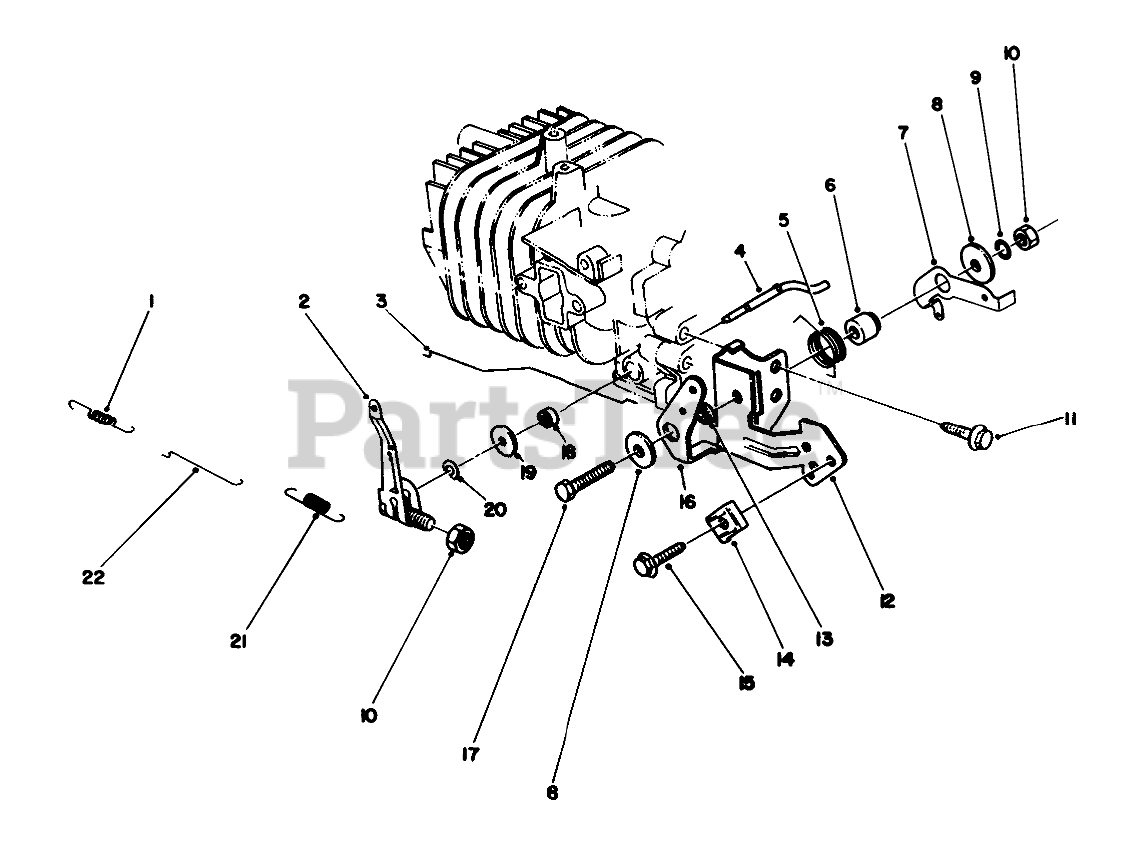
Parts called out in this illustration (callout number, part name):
1	SPRING
2	ARM-GOVERNOR
3	ROD-CHOKE
4	SHAFT
5	SPRING-CHOKE LEVER
6	Gov Lever Spacer
7	LEVER-SPRING, GOVERNOR
8	WASHER
9	LOCKWASHER
12	BRACKET-THROTTLE, CONTROL
13	SPACER-CHOKE LEVER
14	CLAMP
16	LEVER-CONTROL, CHOKE
18	SEAL-OIL
19	WASHER
20	E-RING
21	SPRING-GOVERNOR
22	ROD-CARBURETOR
